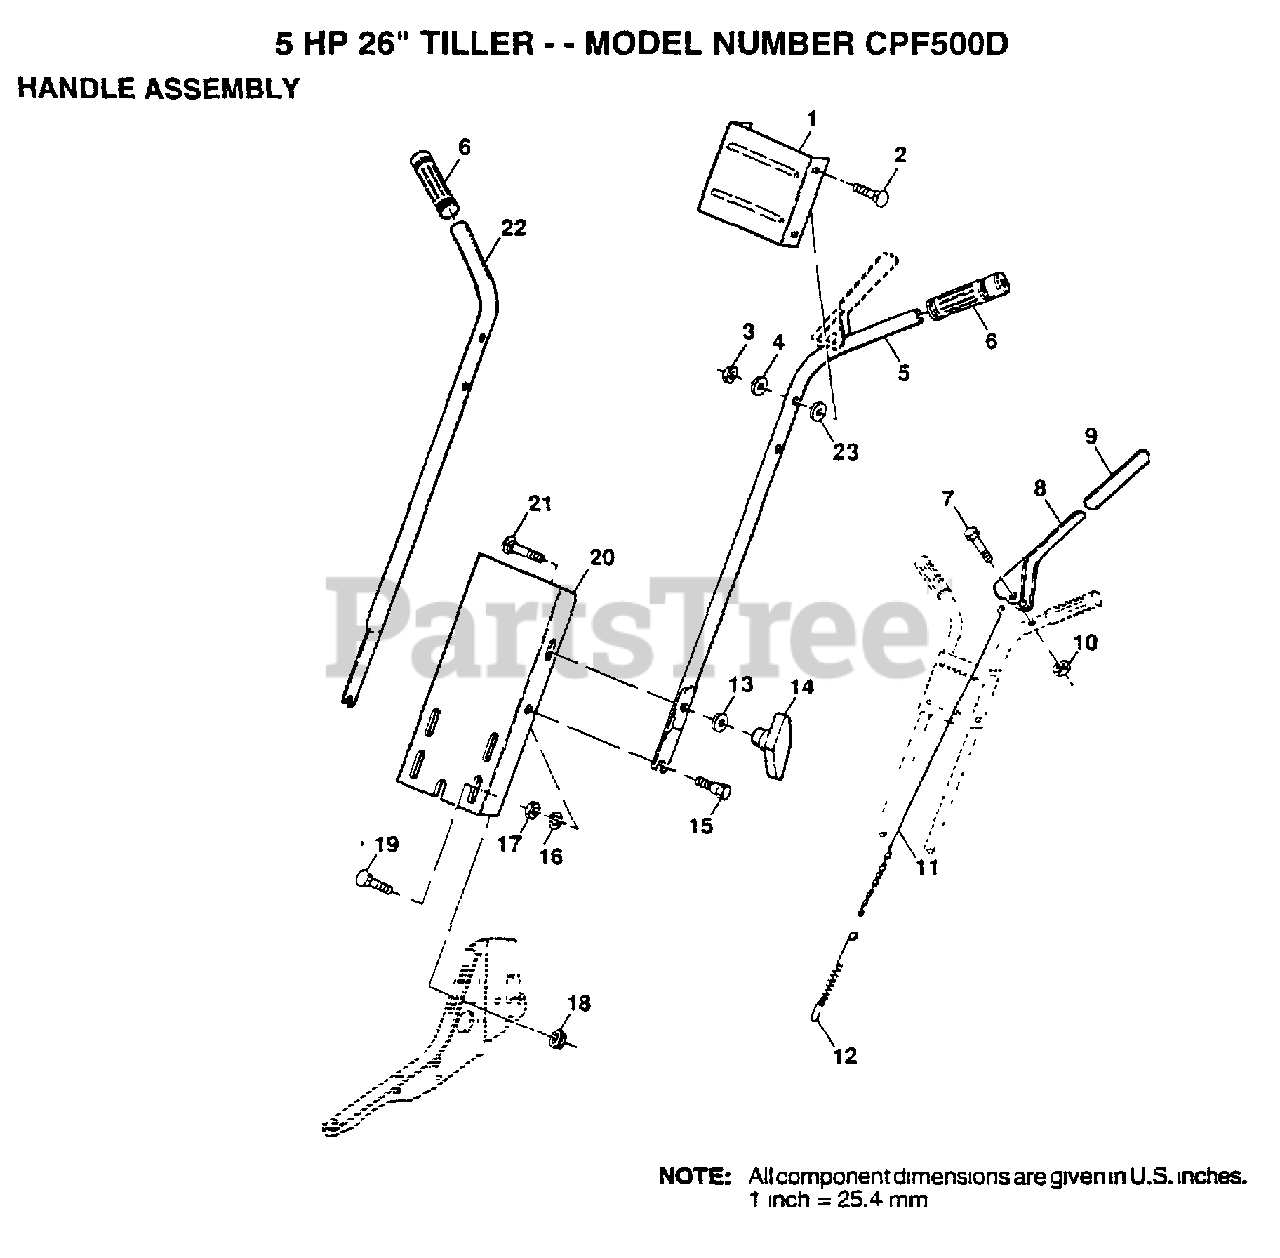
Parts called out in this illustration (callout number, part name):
1	BRACKET.HANDLE
2	BOLT
4	WASHER
6	GRIP NUB DOUBLE
7	BOLT.HEX.5/16-1.5
9	GRIP T
12	SPRING EXT TI
13	WASHER
14	KNOB HANDLE
16	LOCKWASHER
17	NUT.HEX.5/16-18
18	NUT
19	BOLT
21	BOLT CRT
23	WASHER
